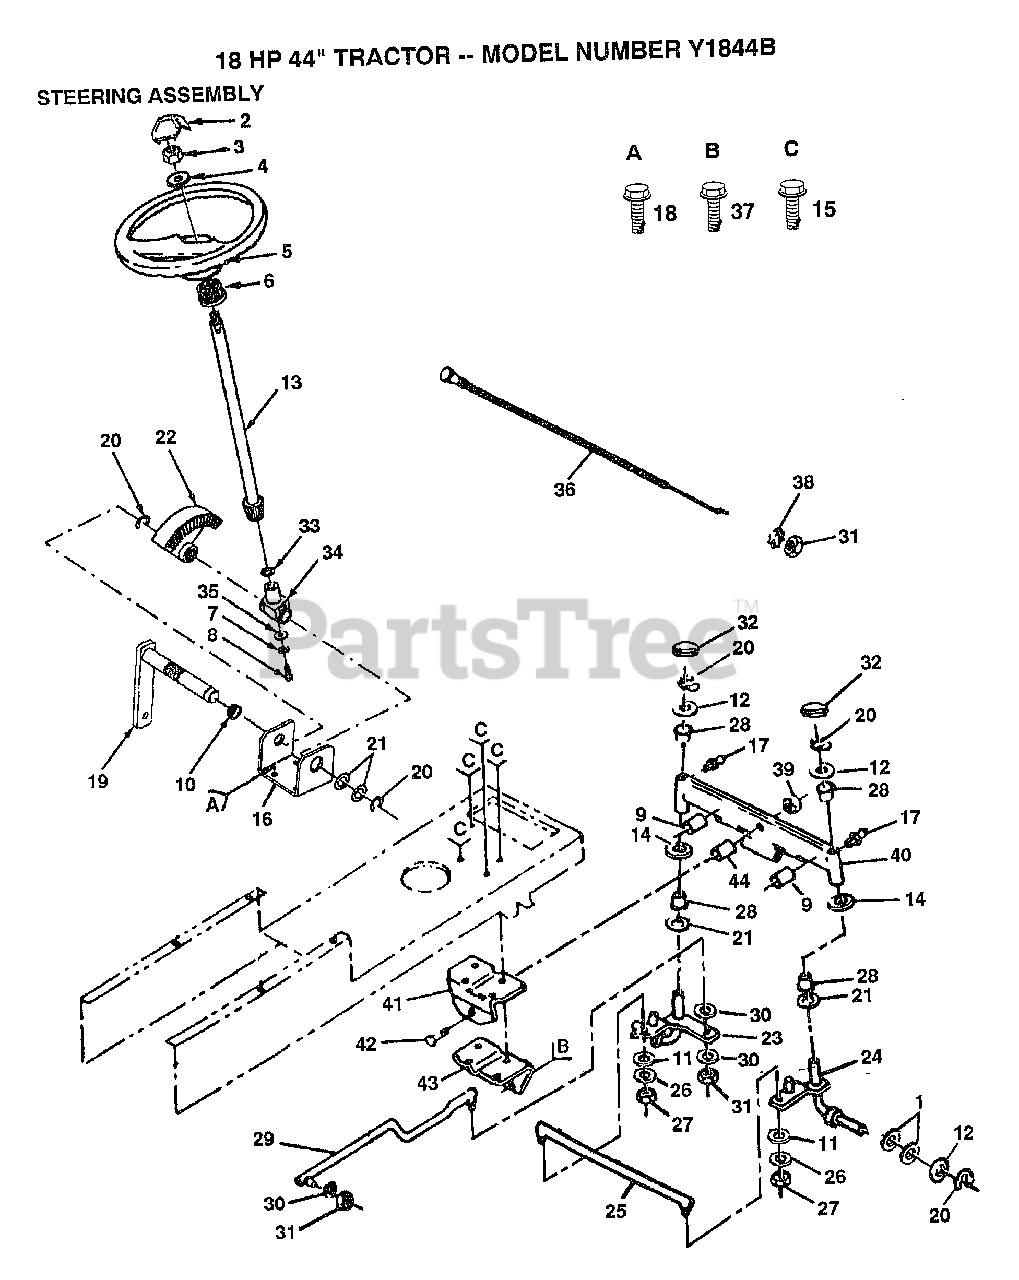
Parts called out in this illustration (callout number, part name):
1	WASHER
2	INSERT STEERING
4	WASHER
6	ADAPTER LT
7	LOCKWASHER
8	"SCREW,SPECIAL"
9	AXLE PIN
10	NYLINER T
11	WASHER M
12	WASHER
14	WASHER
15	SCREW SPECIAL
16	"BRKT,STEERING"
17	ZERK M
18	SCREW
20	RING
21	WASHER .T
23	SPINDLE LH
24	SPINDLE RH
25	TIE ROD
26	LOCKWASHER
27	NUT.LOCK.5/16-24
28	COL. SRTG. BEAR.
30	LOCKWASHER
32	CAP
33	THRUST WASHER
34	SUPPORT.SHAFT
36	CHOKE CONTROL
37	SCREW LT
38	LOCKWASHER
40	FRONT AXLE
41	SUPPORT-SADDL T
42	BOLT LT
43	SUPPORT.SADDLE.FT
44	BEARING
